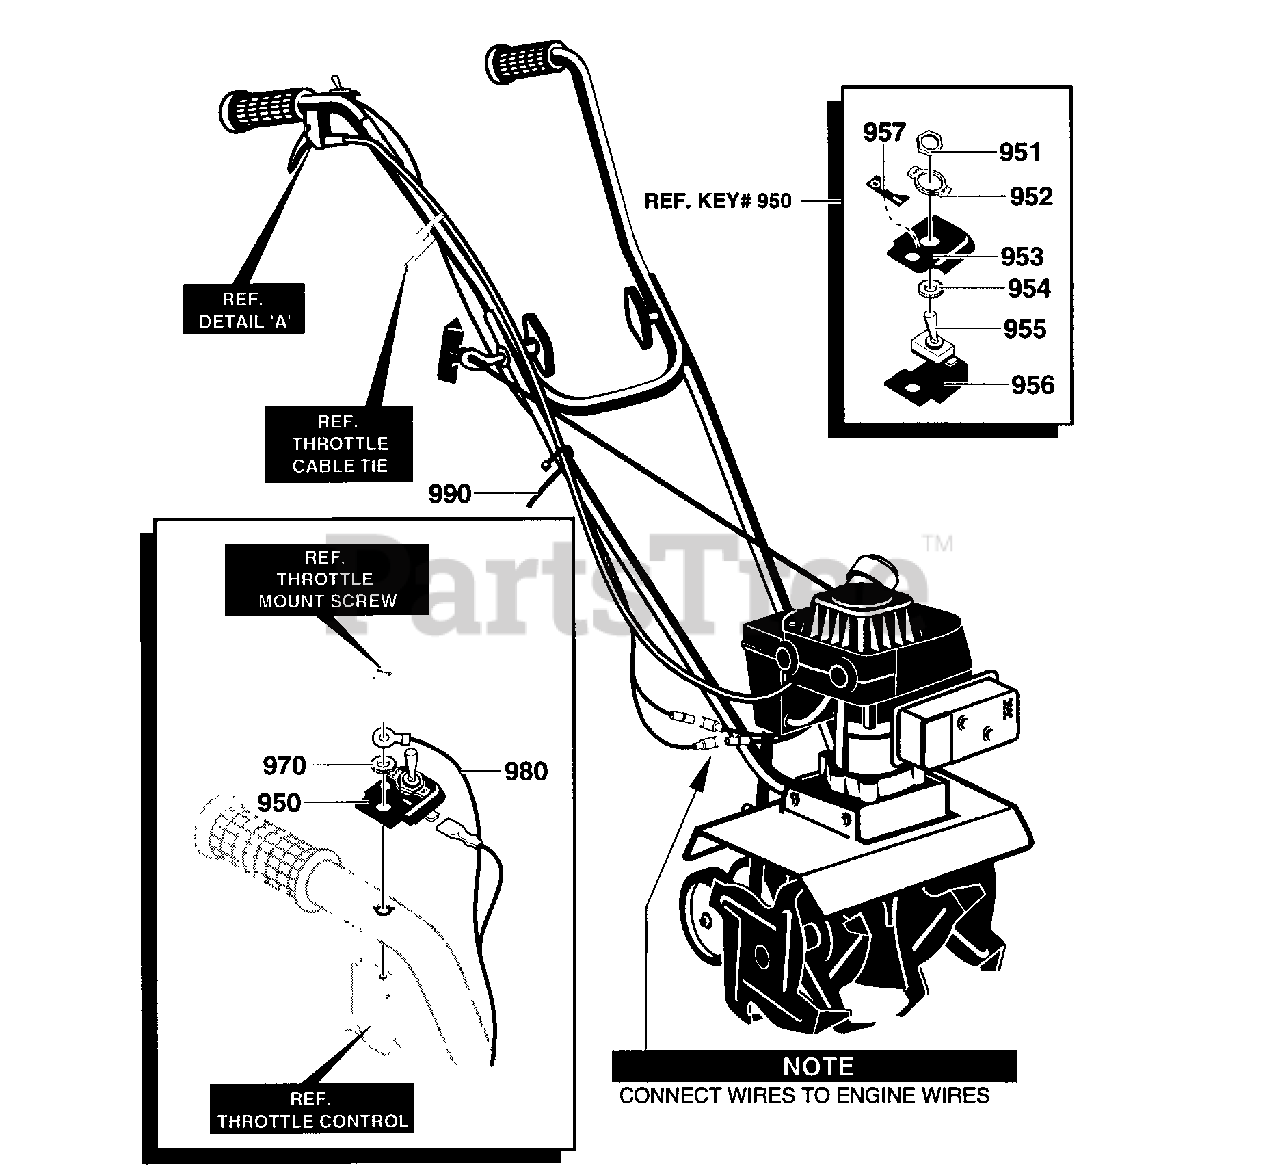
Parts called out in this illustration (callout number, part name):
950	SWITCH ASSEMBLY
951	NUT, MTG 15/32
952	PLATE, INDICATOR
953	BRACKET, SWITCH
954	LOCKWASHER
956	BRACKET, SWITCH
957	DECAL, ON-OFF
970	WASHER, LOCK
980	KILL SWITCH ASSEMBLY
